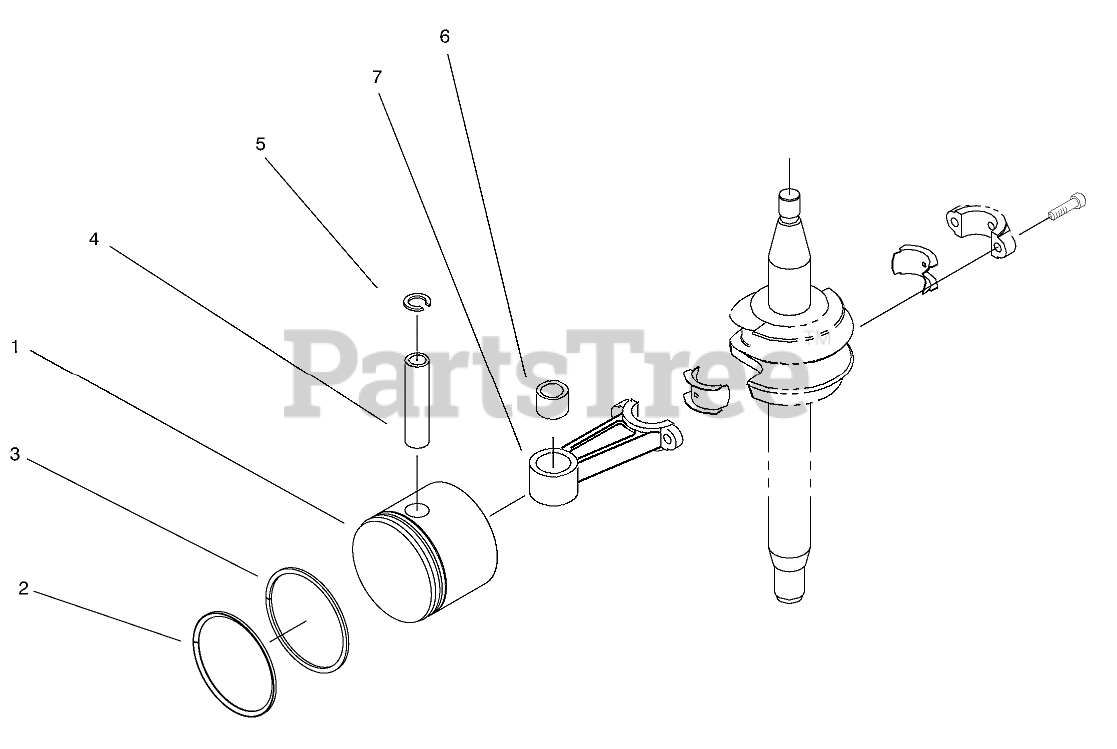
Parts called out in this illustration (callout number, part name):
1	PISTON VF
2	F-RING SET
3	PISTON RING SET S
4	PIN-WRIST VF
5	RING-RETAINING
6	BEARING XEV
7	CONNECTING ROD ASM
